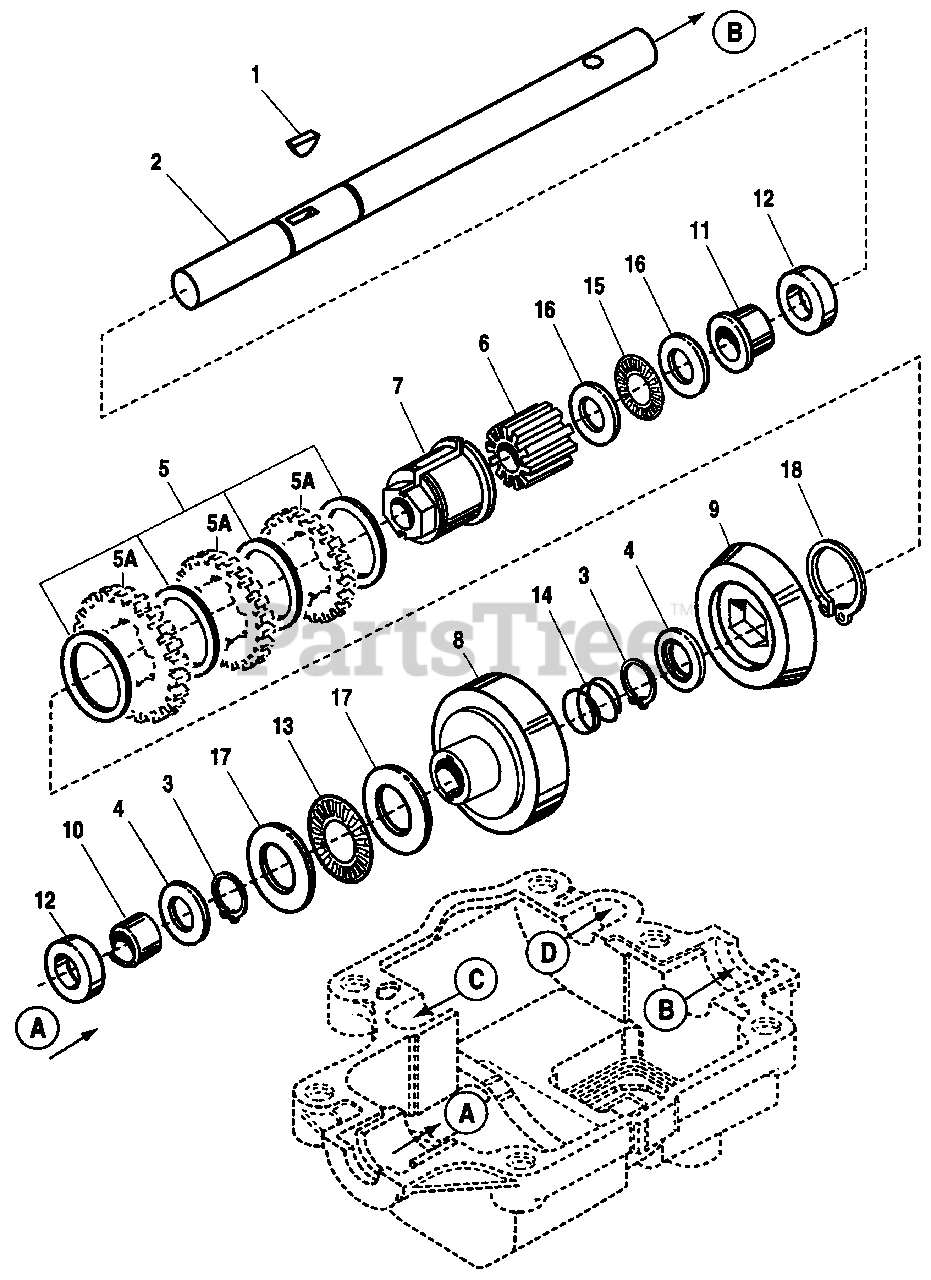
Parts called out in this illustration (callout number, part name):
1	KEY, Woodruff
2	AXLE, Shaft
4	WASHER, Retainer
5A	GEAR SET
6	SUPPORT, Key
7	COLLAR, Shift
13	THRUST NEEDLE
14	SPRING, Return
15	THRUST NEEDLE
16	WASHER, Thrust
17	WASHER, Thrust
